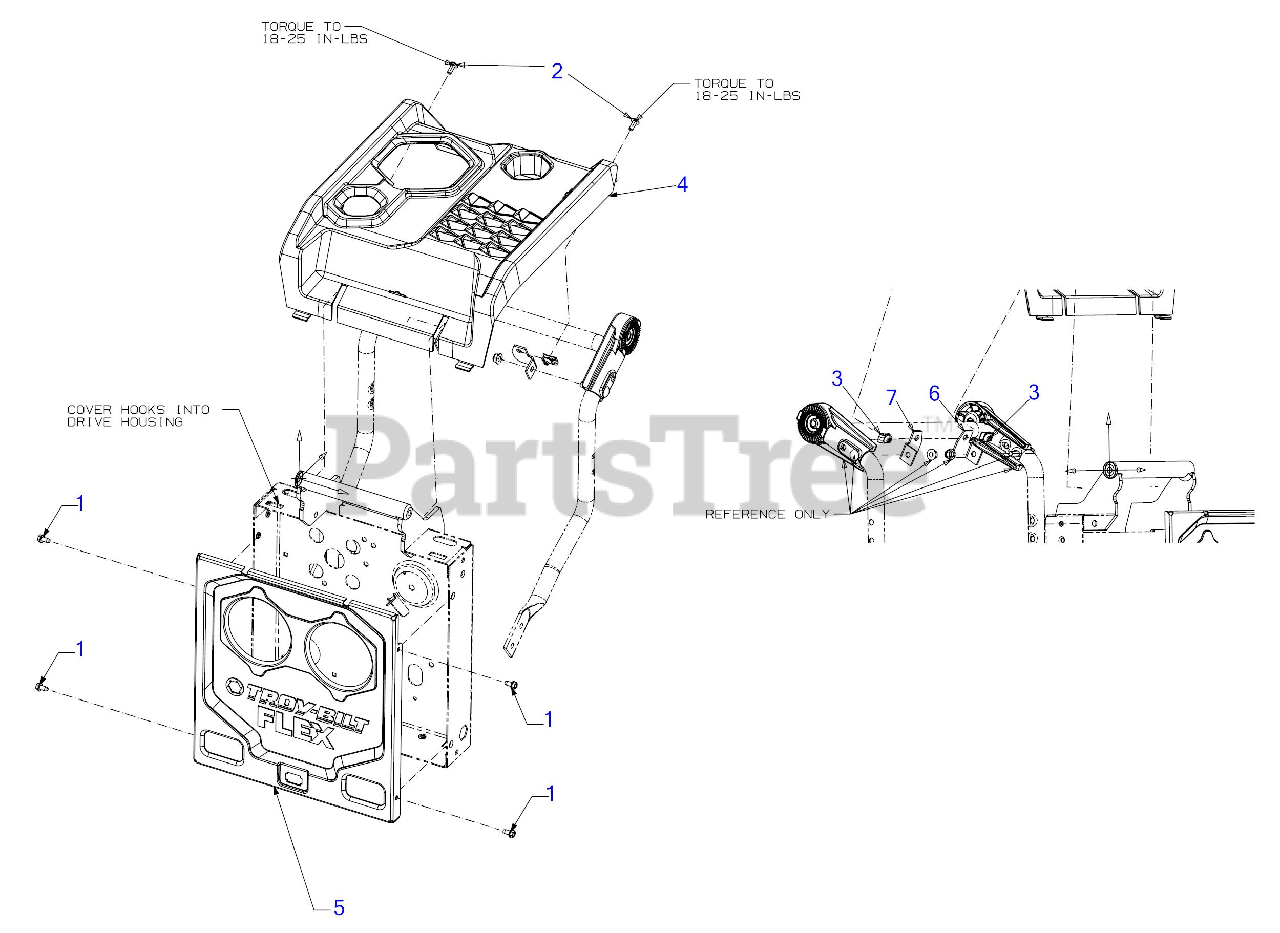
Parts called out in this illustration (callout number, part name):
1	SCREW 1/4-20 X.500
2	SCREW 1/4-20 x .625
3	U-CLIP NUT
